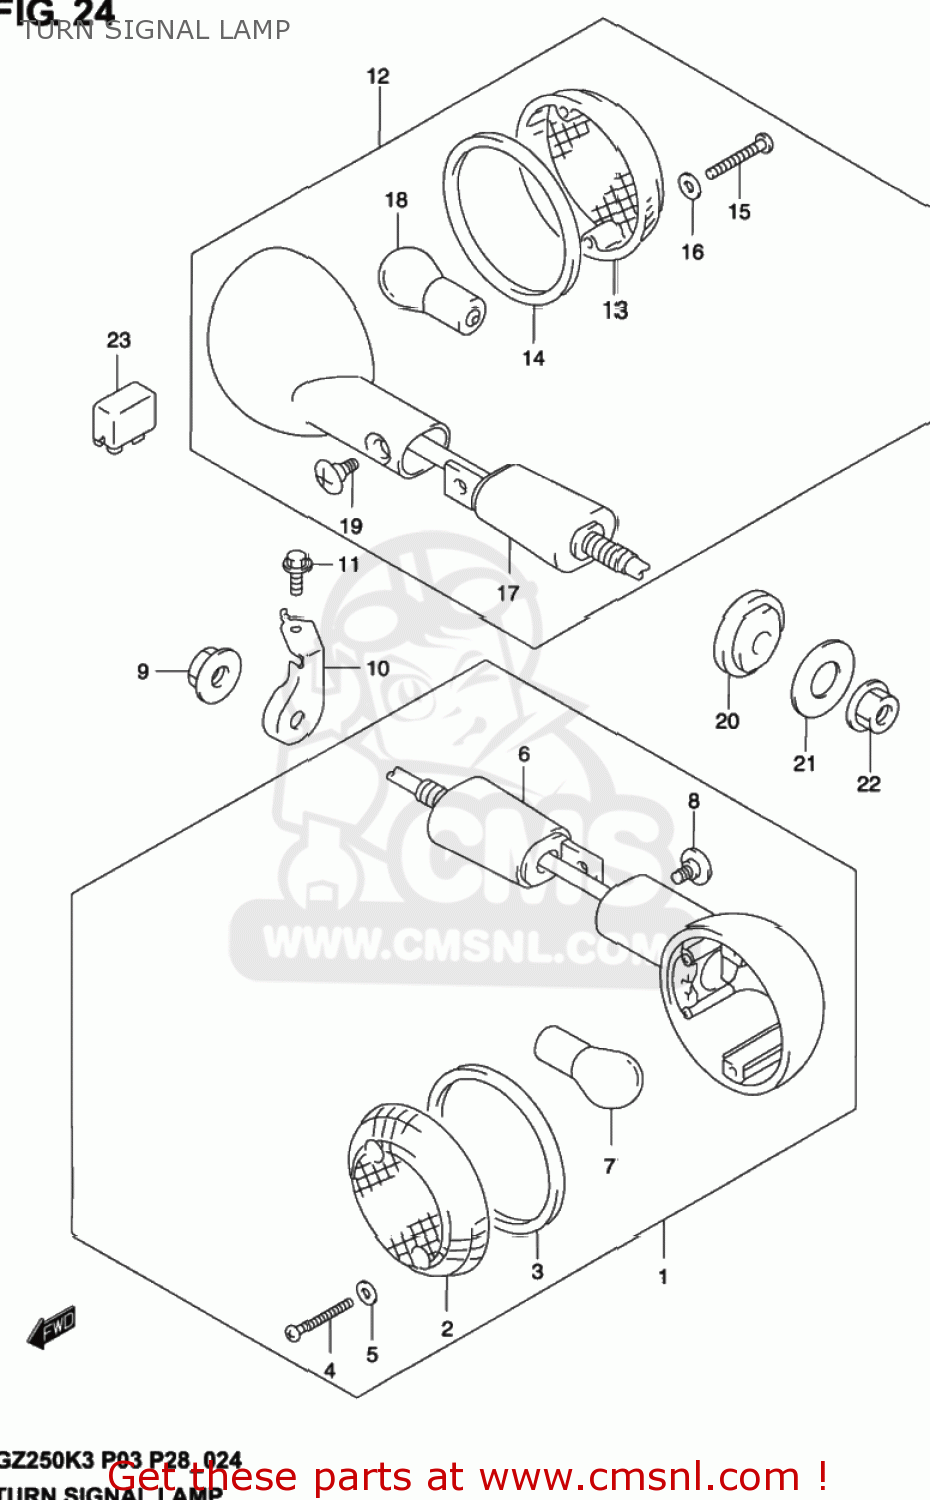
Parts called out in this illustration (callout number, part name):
1	LAMP ASSY,FR TURN SIGNAL,R
2	LENS
3	GASKET (NAS)
4	SCREW
5	GASKET (NAS)
6	STAY,TURNSIGNAL FR
7	BULB(12V21/5W)
8	SCREW
9	NUT
10	BRACKET,FR TURNSIGNAL,R
11	BOLT
12	LAMP ASSY,RR TURNSIGNAL,R
13	LENS
14	GASKET (NAS)
15	SCREW
16	GASKET (NAS)
17	STAY,TURNSIGNAL RR
18	BULB(12V21W)
19	SCREW
20	SPACER,RR TURNSIGNAL
21	WASHER(10.5X30X2.3)
22	NUT
23	RELAY ASSY,TURNSIGNAL LAMP
